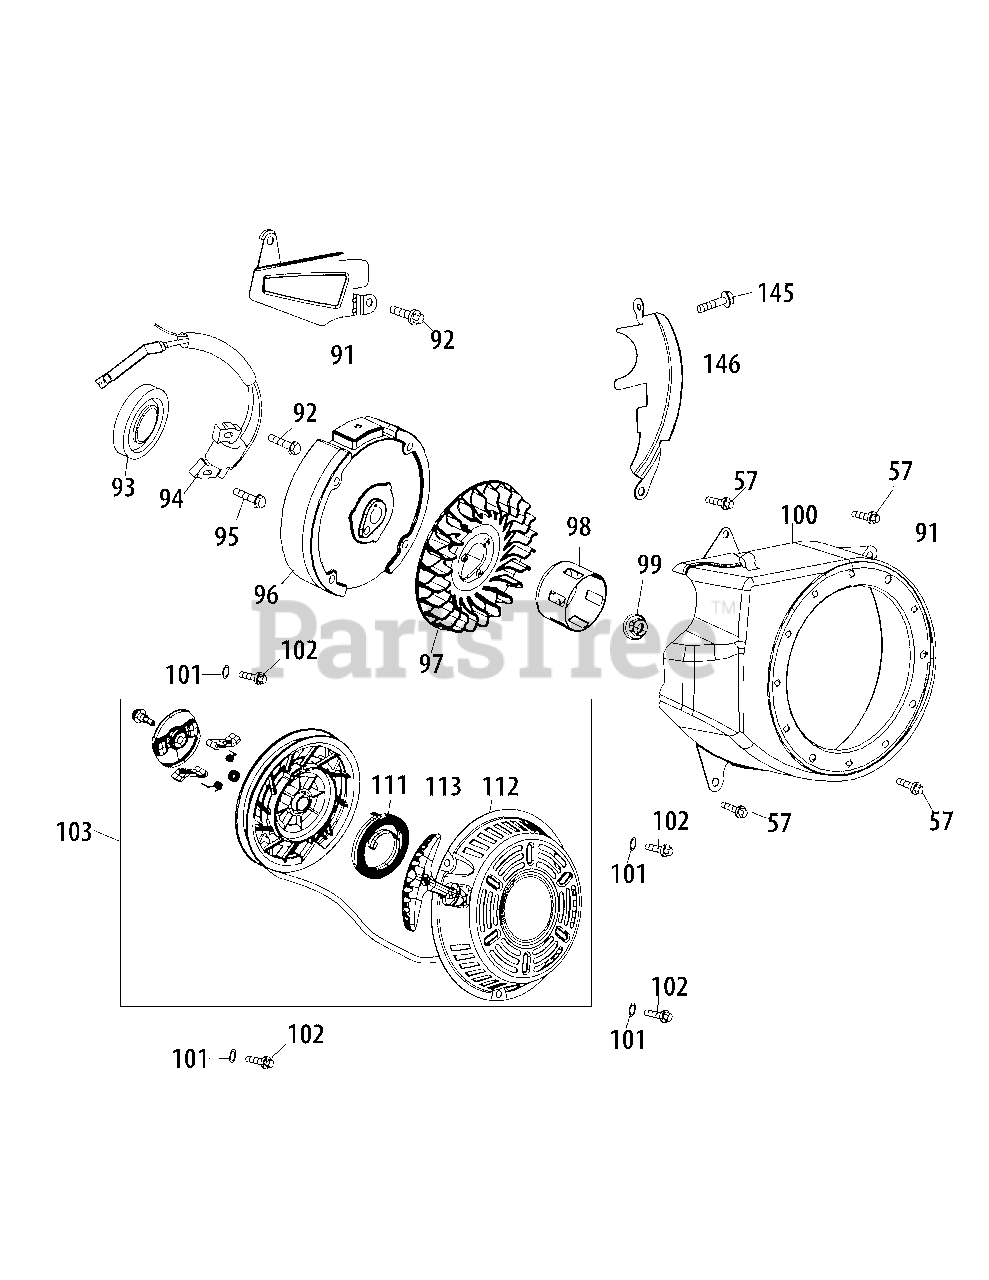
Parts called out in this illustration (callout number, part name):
57	Bolt M6×12
91	Air Flow Shield
92	Bolt M6×10
93	Oil Seal 25×41.25×6
94	Ignition Coil Assembly
95	Bolt M6×25
97	Cooling Fan
98	Starter Cup
99	Flywheel Nut, M14 X 1.5
100	Blower Housing
101	Washer
102	Bolt M6×10
103	Recoil Starter
111	Recoil Spring
112	Recoil Housing
113	Starter Handle
145	Bolt M6×20
146	Lower Shield
